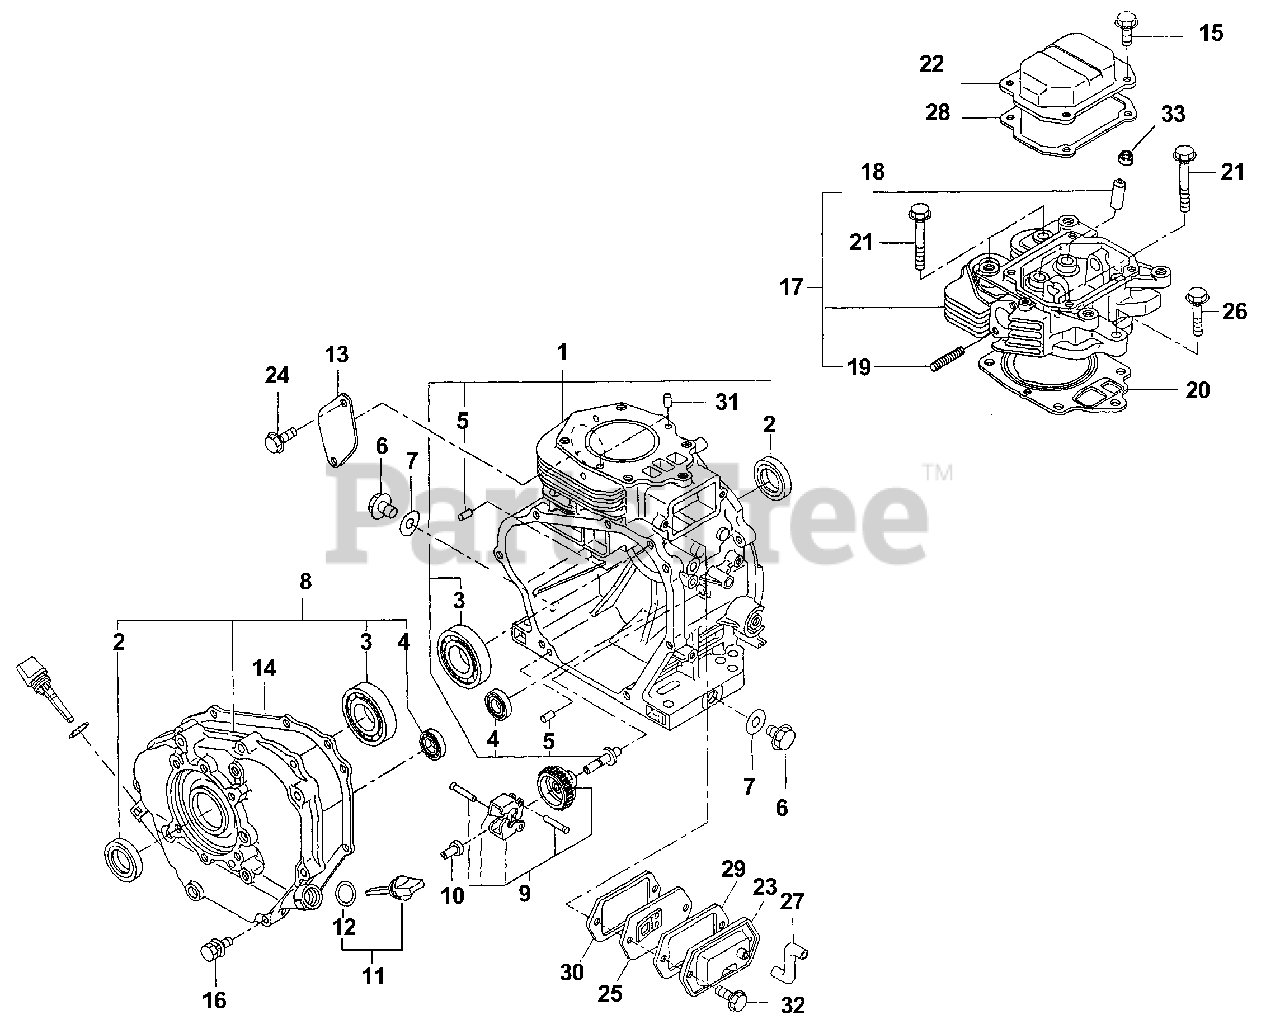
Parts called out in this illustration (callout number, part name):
1	Crankcase
2	Oil seal
3	Ball bearing
4	Ball bearing
5	Dowel pin
6	Plug
7	Gasket
8	Main bearing cover
9	Governor gear cp
10	Governor sleeve
11	Oil gauge
12	Gasket
13	Blind cover
14	Bearing cover gasket
15	Flange, bolt
16	Bolt and washer ay
17	Cylinder head
18	Valve guide
19	Stud
20	Head gasket
21	Flange bolt
22	Rocker cover cp
23	Breather Cover Cp
24	Bolt
25	Breather Plate Cp
26	Flange bolt
27	Rubber pipe
28	Gasket rocker cover
29	Gasket breather cover
30	Gasket breather plate
31	Dowel pin
32	Flange bolt
